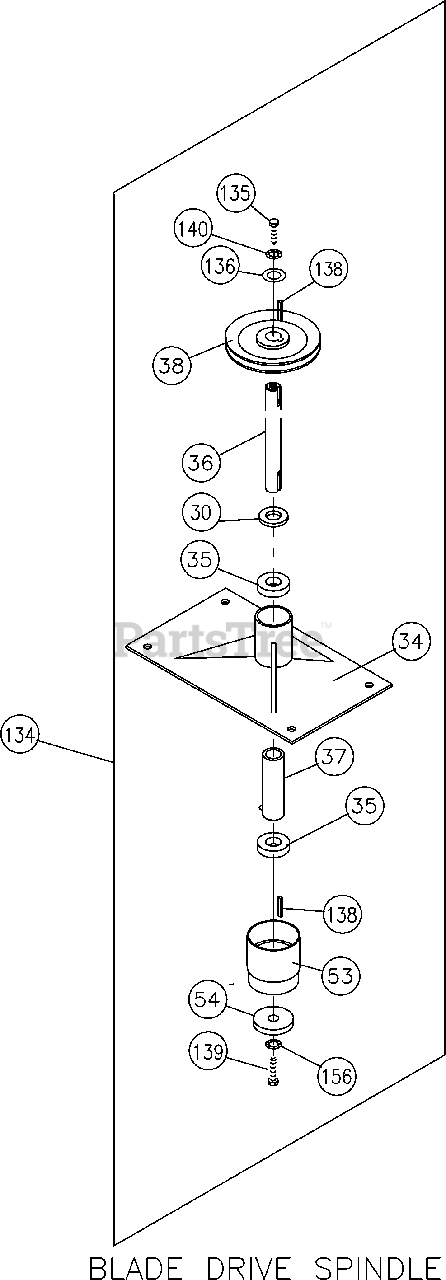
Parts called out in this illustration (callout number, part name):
30	Spacer Spindle BC2402
34	Spindle WA BC2402
35	Bearing 7/8" ID Sealed Press
36	Shaft Drive Blade
37	Spacer Spindle Bearing
38	Pulley 7" OD x 7/8" Bore
53	Adapter Blade WA
54	Washer Friction Blade
134	Spindle Assembly Complete
135	Screw Cap 7/16-20 x 1-1/4” GR8
136	Washer 7/8 SAE
138	Key Sq 3/16 x 5/8”
139	Screw Cap 7/16-20 x 2” GR8
140	Washer Lock 7/16”
156	Washer lock 7/16 S/T Med
